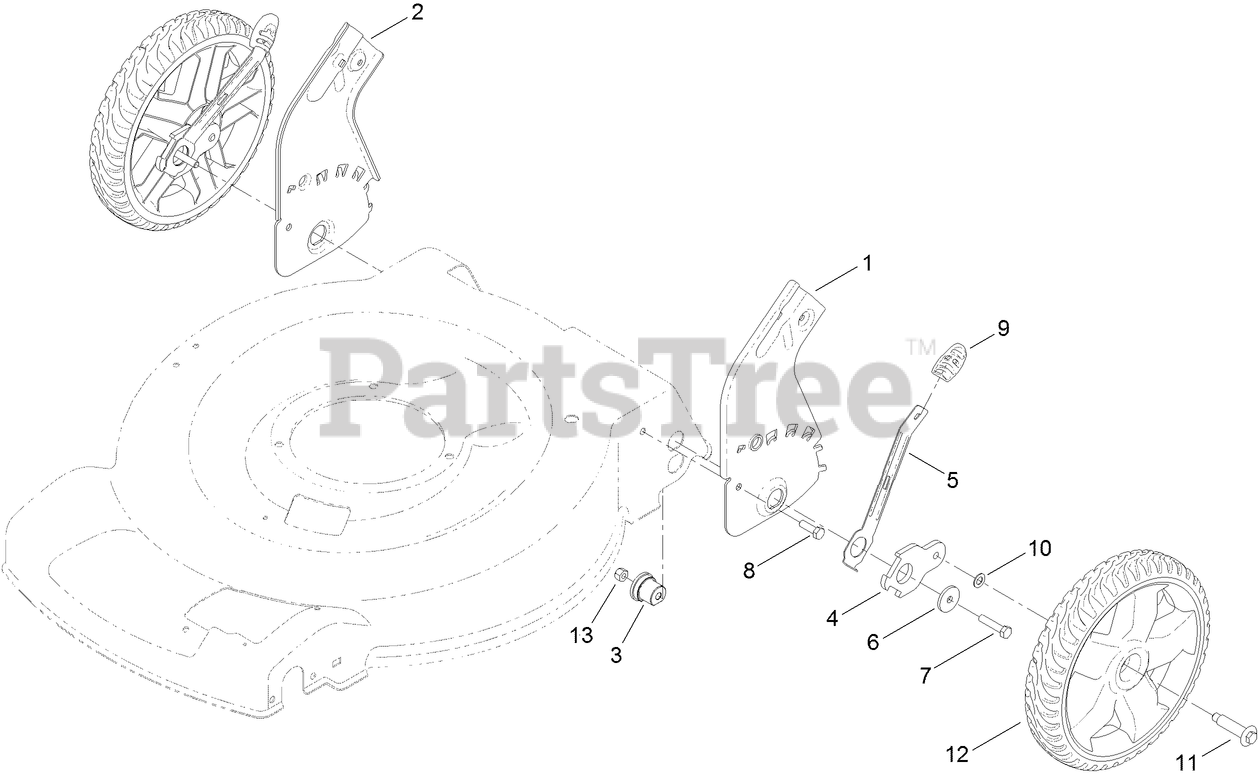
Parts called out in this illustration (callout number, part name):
1	PLATE-HOC, REAR (LH)
2	PLATE-HOC, REAR (RH)
3	BUSHING-MOUNT, HOC
5	ARM-SPRING, REAR
6	WASHER-FLAT
7	SCREW-HH
8	SCREW-HH
9	KNOB-LEVER, HOC
10	WASHER
11	BOLT-SHOULDER
13	NUT-LOCK, NI
